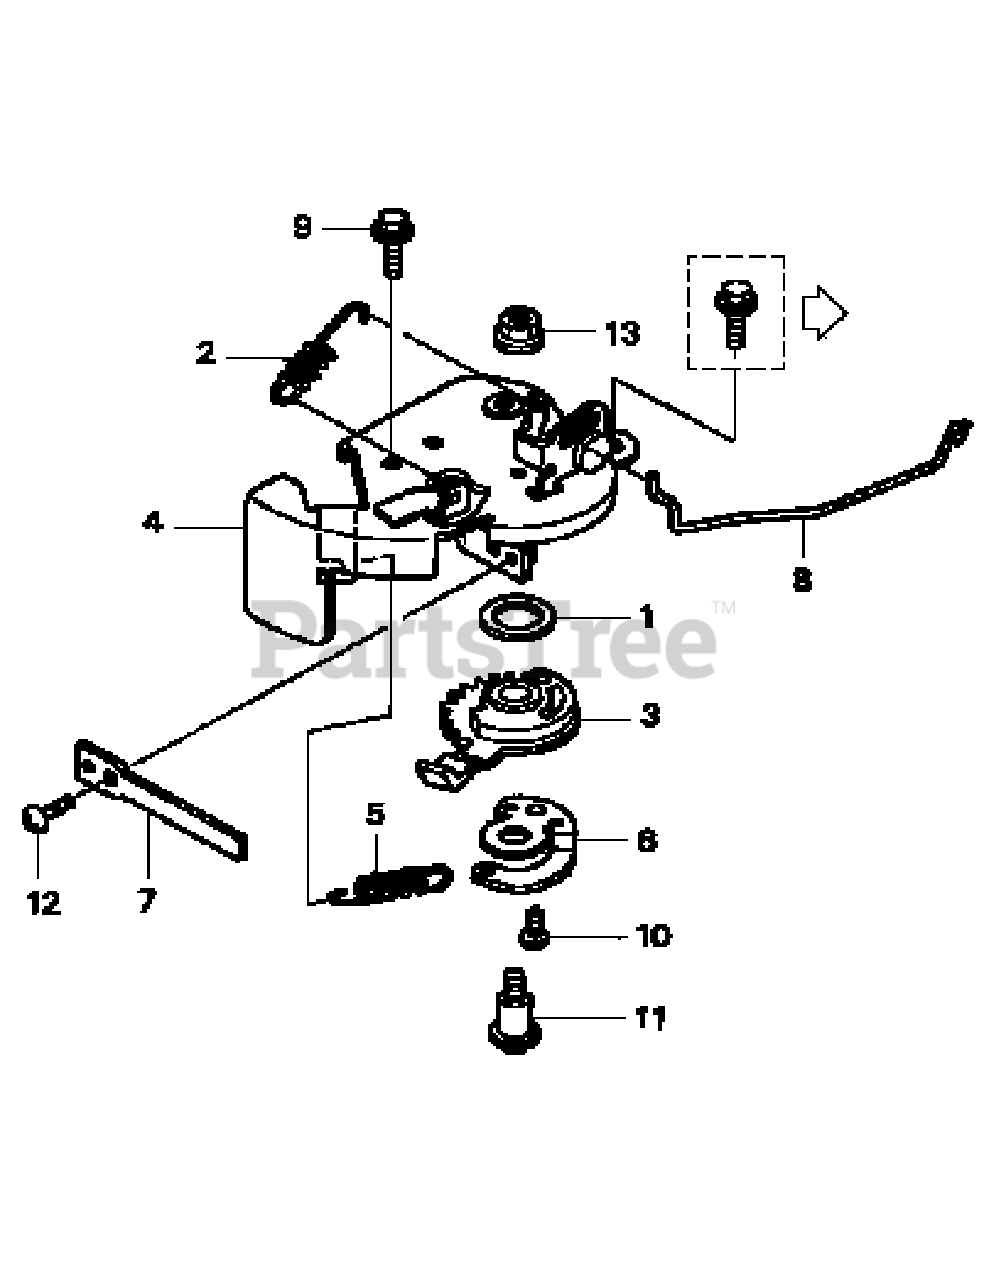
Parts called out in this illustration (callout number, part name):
1	Choke Lever Seal
2	Cable Return Spring
3	Choke Lever
4	Choke Base
5	Choke Lever Spring
6	Choke Spring Hook
7	Choke Plate
8	Stop Rod
9	Flange Bolt (6x16)
10	Tapping Screw (4x8)
11	Pan Screw (5x19)
12	Pan Screw (4x8)
13	Flange Nut (5mm)
